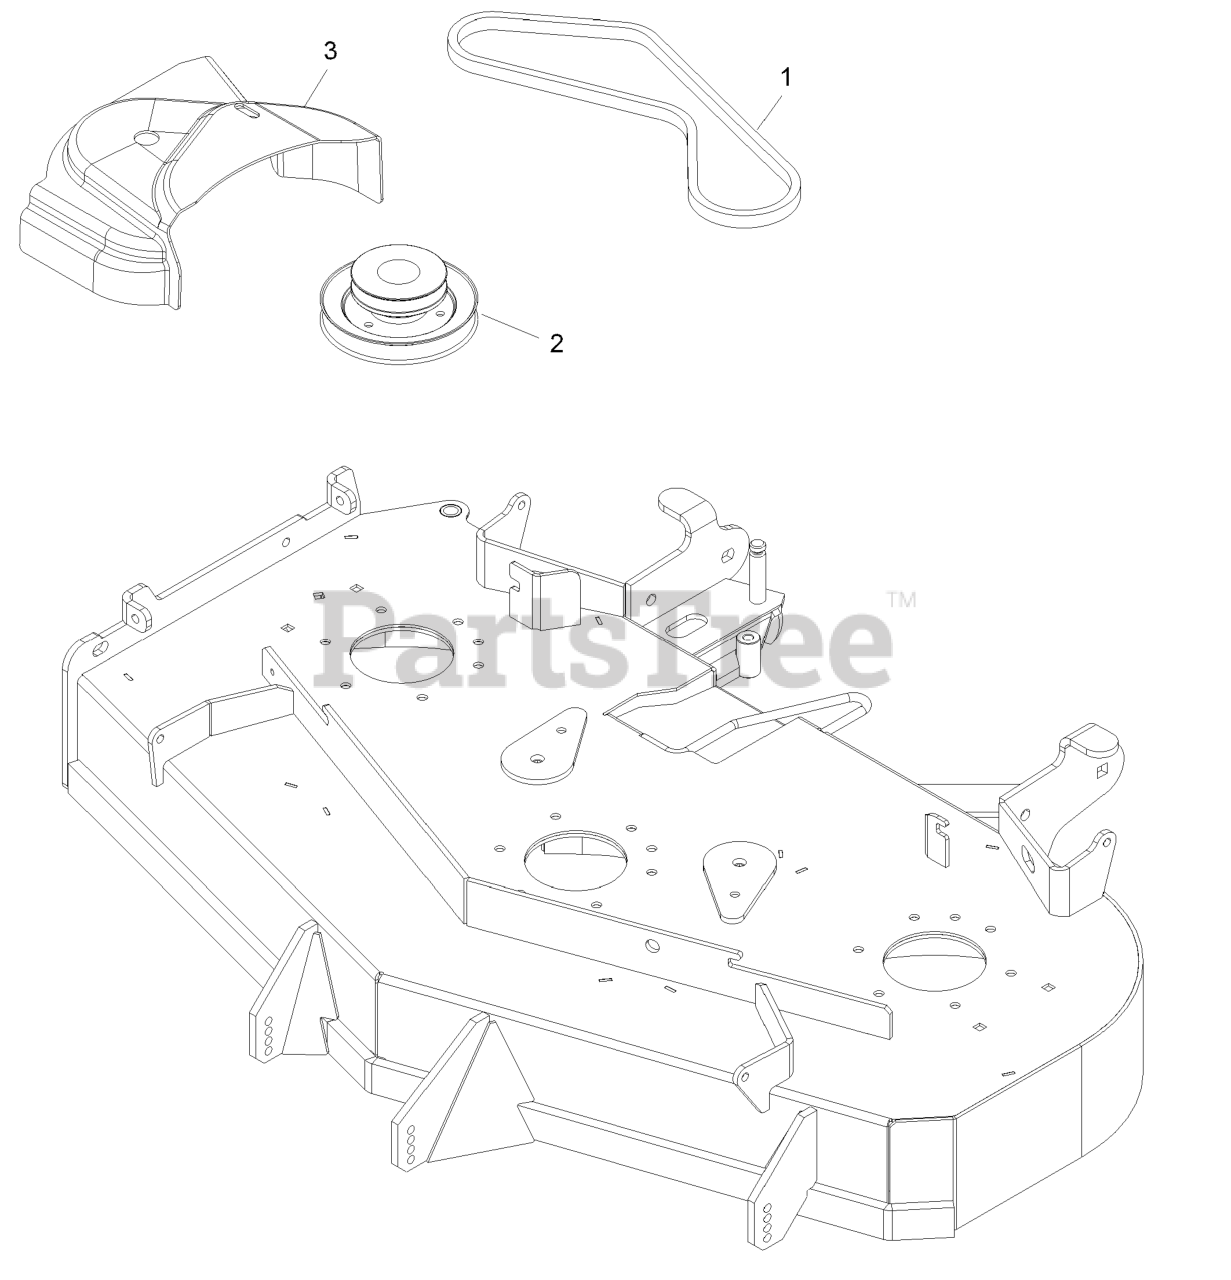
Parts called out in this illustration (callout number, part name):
1	BELT-BLOWER
2	JACKSHAFT,UV DRIVE 484
3	COVER,BELT UV 48
